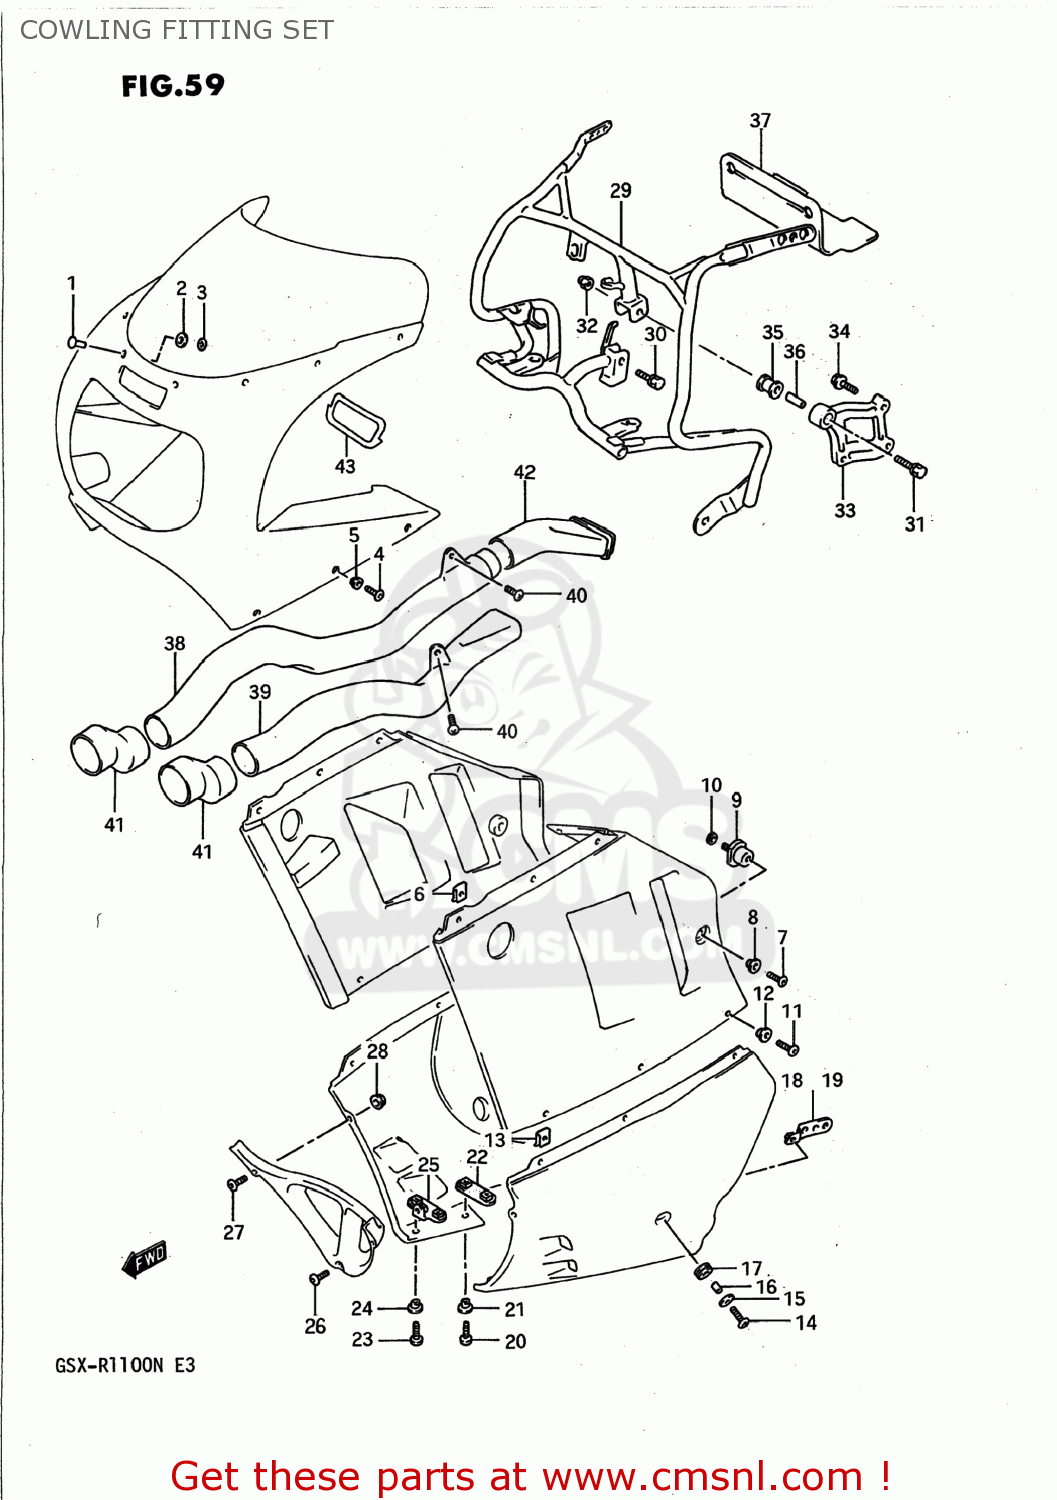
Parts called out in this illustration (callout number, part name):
1	PIN,WINDSCREEN
2	CUSHION
3	NUT
4	SCREW(5X18)
5	WASHER(5.2X14X1.5)
6	NUT,HEADLAMP HOUSING,UPPER
7	SCREW(6X12)
8	WASHER(6.3X16X1.5)
9	CUSHION,COWLING
10	WASHER,LOCK
11	SCREW(5X18)
12	WASHER(5.2X14X1.5)
13	NUT,HEADLAMP HOUSING,UPPER
14	SCREW(6X20)
15	WASHER(6.5X18X1)
16	SPACER
17	CUSHION
18	BRACE,COWLING LWR,R
19	BRACE,COWLING LWR,L
20	SCREW(6X16)
21	WASHER(6.3X16X1.5)
22	BRACE,COWLING LWR COVER RR
23	SCREW(6X16)
24	WASHER(6.3X16X1.5)
25	BRACE,COWLING LWR COVER
26	SCREW(6X16)
27	SCREW(5X14)
28	NUT
29	BRACE,COWLING
30	BOLT, BRACE (8X30)
31	BOLT
32	NUT ,8MM
33	BRACE,COWLING CTR
34	BOLT, BRACE CENTER (8X40)
35	CUSHION,COWLING BRACE
36	SPACER
37	SHEET,COWLING HEAT GUARD
38	PIPE,AIR INTAKE FR,R
39	PIPE,AIR INTAKE FR,L
40	SCREW, CENTER
41	JOINT,AIR INTAKE
42	PIPE,AIR INTAKE RR,R
43	CUSHION,FR POSITION LAMP
